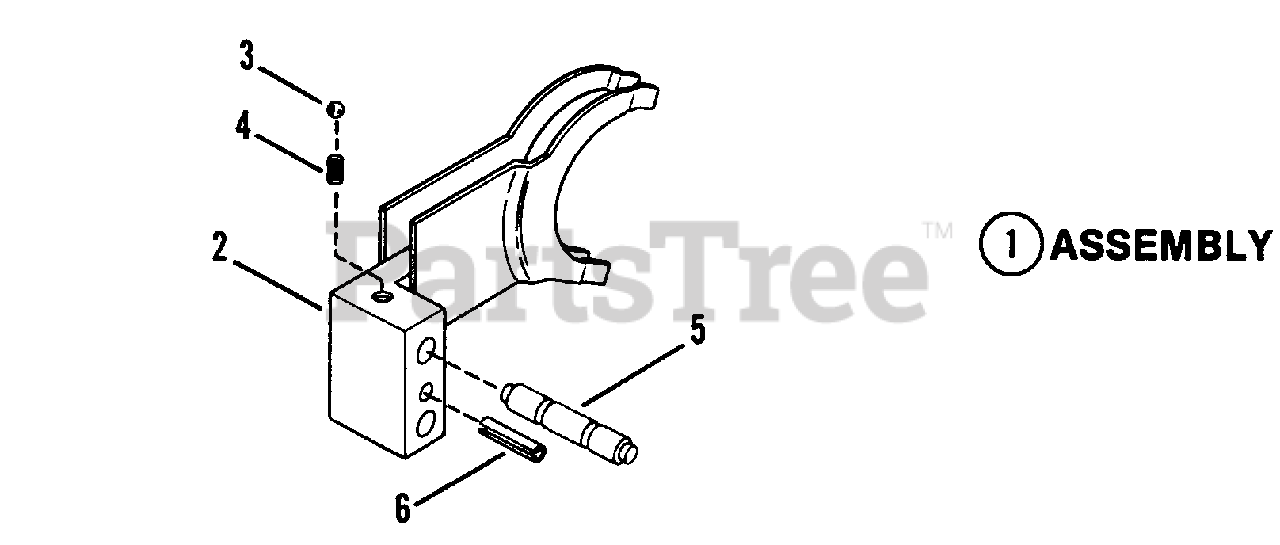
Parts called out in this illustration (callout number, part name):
1	ASSEMBLY, HI-LO SHIFTER
2	FORK, Shift
3	BALL, Detent
4	SPRING, Detent Ball
5	GUIDE-PIN, Detent
6	ROLL-PIN, 1/4x1-1/4
